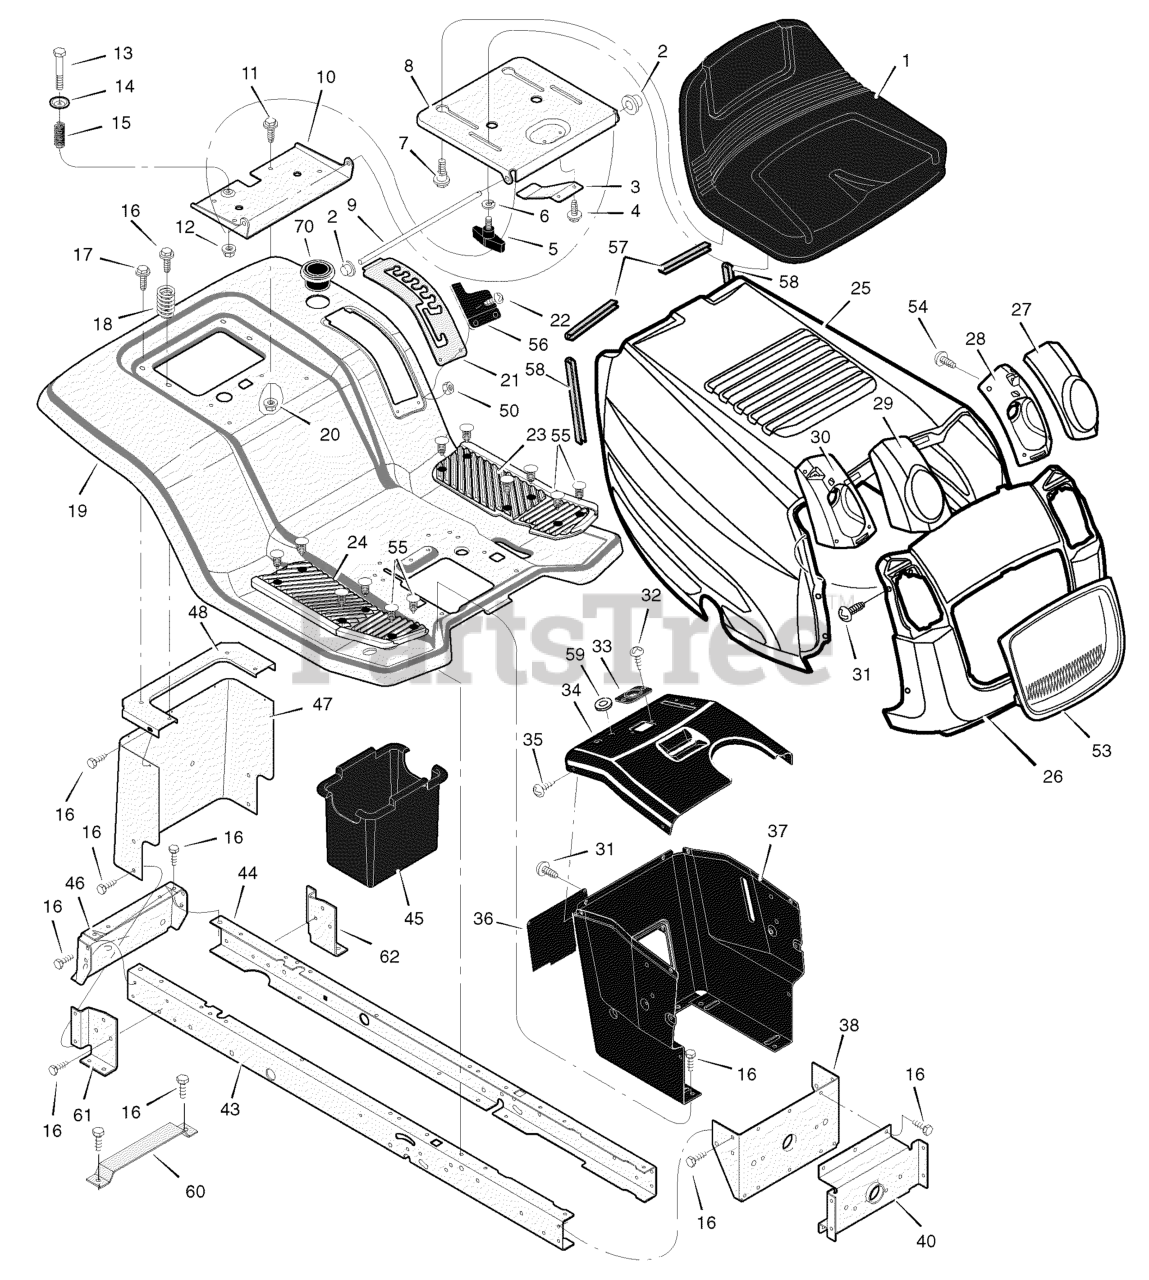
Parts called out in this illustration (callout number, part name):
2	Cap, Push 0n
3	Spring
4	Screw
5	Bolt, Wing
6	Washer
7	Bolt, Shoulder
8	Support, Seat
9	Rod, Pivot
10	Bracket, Pivot
11	Bolt
12	Nut
13	Bolt, Shoulder
15	Spring
16	Screw
17	Screw
18	Spring
19	Deck, Seat
20	Nut
21	Plate, Index
22	Screw
23	Mat, Left
24	Mat, Right
27	Lens, Left
28	Housing, Left Headlamp
29	Lens, Right
30	Housing, Right Headlamp
31	Screw
33	Bearing, Steering
35	Screw
36	Panel, Access
37	Support, Dash
38	Bracket, Rear Hanger
40	Axle, Hanger
43	Frame, Right
44	Frame, Left
45	Container, Battery
46	Plate, Hitch
47	Plate, Rear
48	Top, Rear Plate
50	Nut
53	Insert, Grille
54	Screw
55	Fastener, Panel
56	Cover, Detent
57	Trim, Hood (3.75")
58	Trim, Hood (6.5")
59	Grommet, Parking Brake
60	Bracket, Support
61	Bracket, Right Transaxle
62	Bracket, Left Transaxle
70	Holder, Cup
